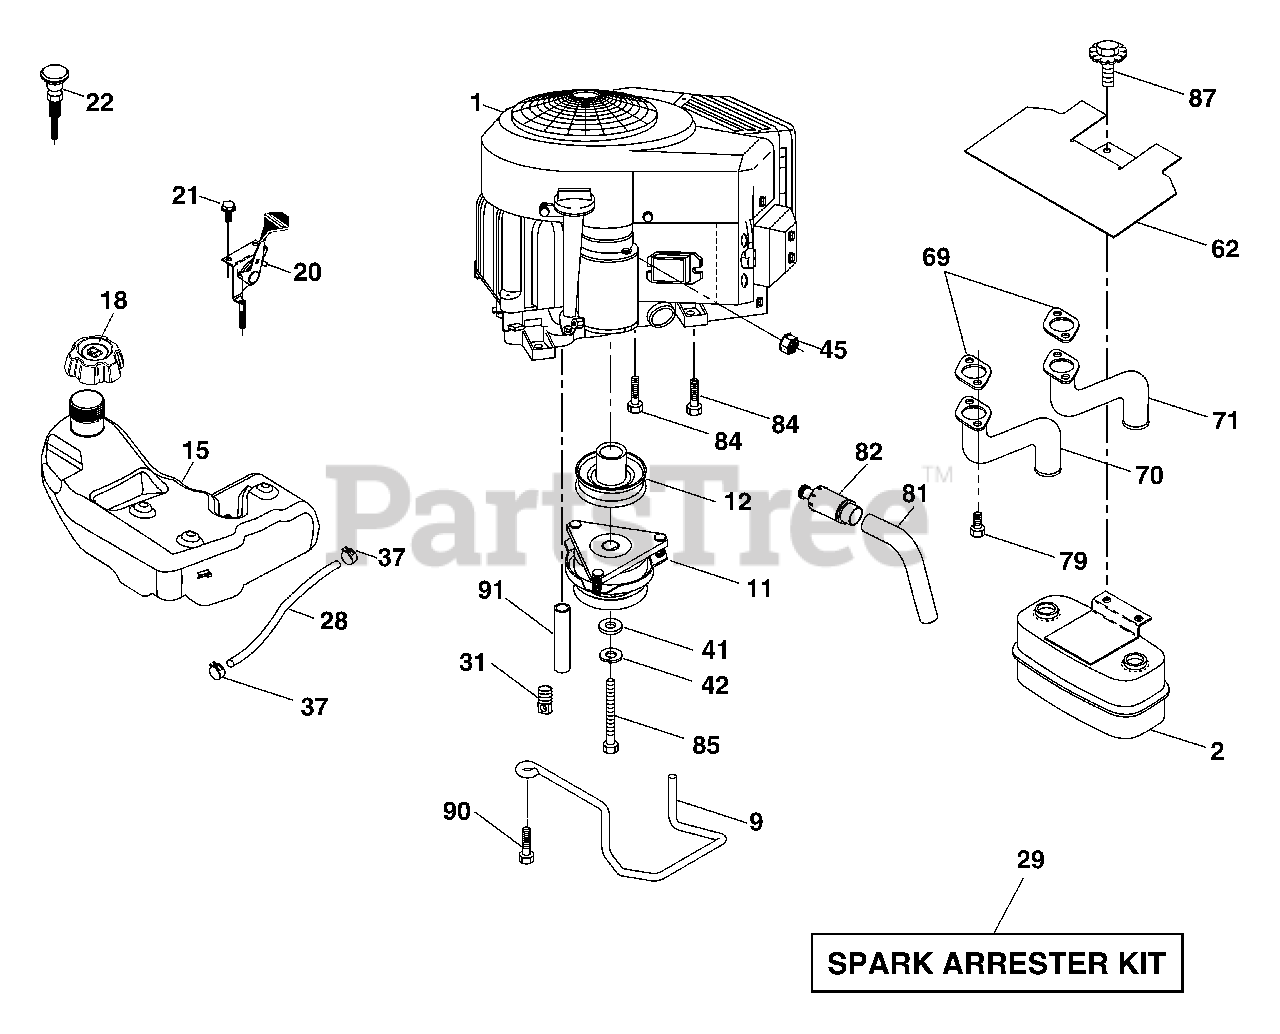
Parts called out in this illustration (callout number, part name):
9	Keeper Belt Engine
11	Clutch Electric
12	Pulley Engine
15	Tank Fuel 4.0
18	Cap Asm
20	Control Throttle
21	Screw 10 x 3/4 Single Lead Hex
22	Control Choke
28	Fuel Line
29	Spark Arrester Kit
31	Clip Push-In
37	Clamp Hose
41	Washer 1-1/2 OD x 15/32 ID x .250
42	Washer Lock 7/16
45	Nut Keps Hex 1/4-20 unc
62	Shield Heat Muffler
70	Tube Exhaust LH
71	Tube Exhaust RH
79	Screw Socket Head 5/16-18 x 1
81	Tube Drain Oil Easy
82	Plug Drain Oil
84	Screw 3/8-16 x 1/2
85	Bolt Hex 7/16-20 x 3.75 Gr. 5
87	Bolt 5/16-18 unc x 1 w/Sems
90	Screw 3/8-16 x 1
